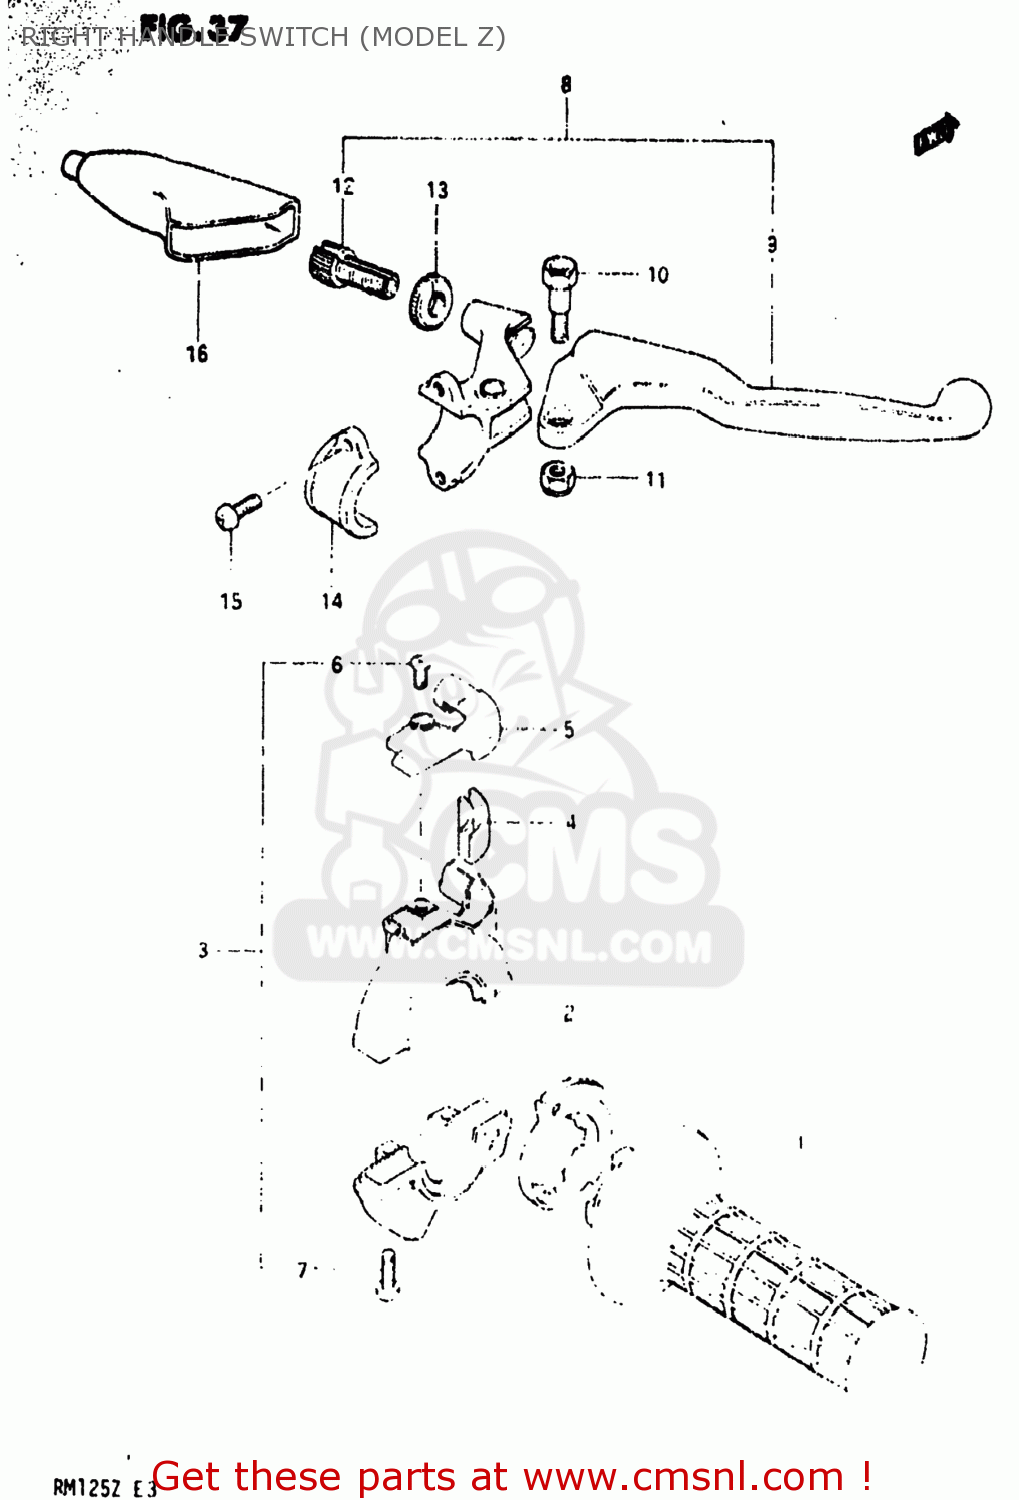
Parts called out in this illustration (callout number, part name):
1	GRIP,THROTTLE
2	ROTOR,THROTTLE GRIP
3	CASE ASSEMBLY,THROTTLE
4	GUIDE PIECE,THROTTLE
5	COVER,THROTTLE CASE
6	SCREW
7	SCREW
8	LEVER ASSEMBLY,BRAKE
9	LEVER,BRAKE
10	BOLT,LEVER
11	NUT 6MM
12	ADJUSTER,CABLE
13	NUT,CABLE ADJUSTER
14	BRACKET,CLUTCH LEVER HOLDER
15	SCREW
16	COVER,CLUTCH LEVER
